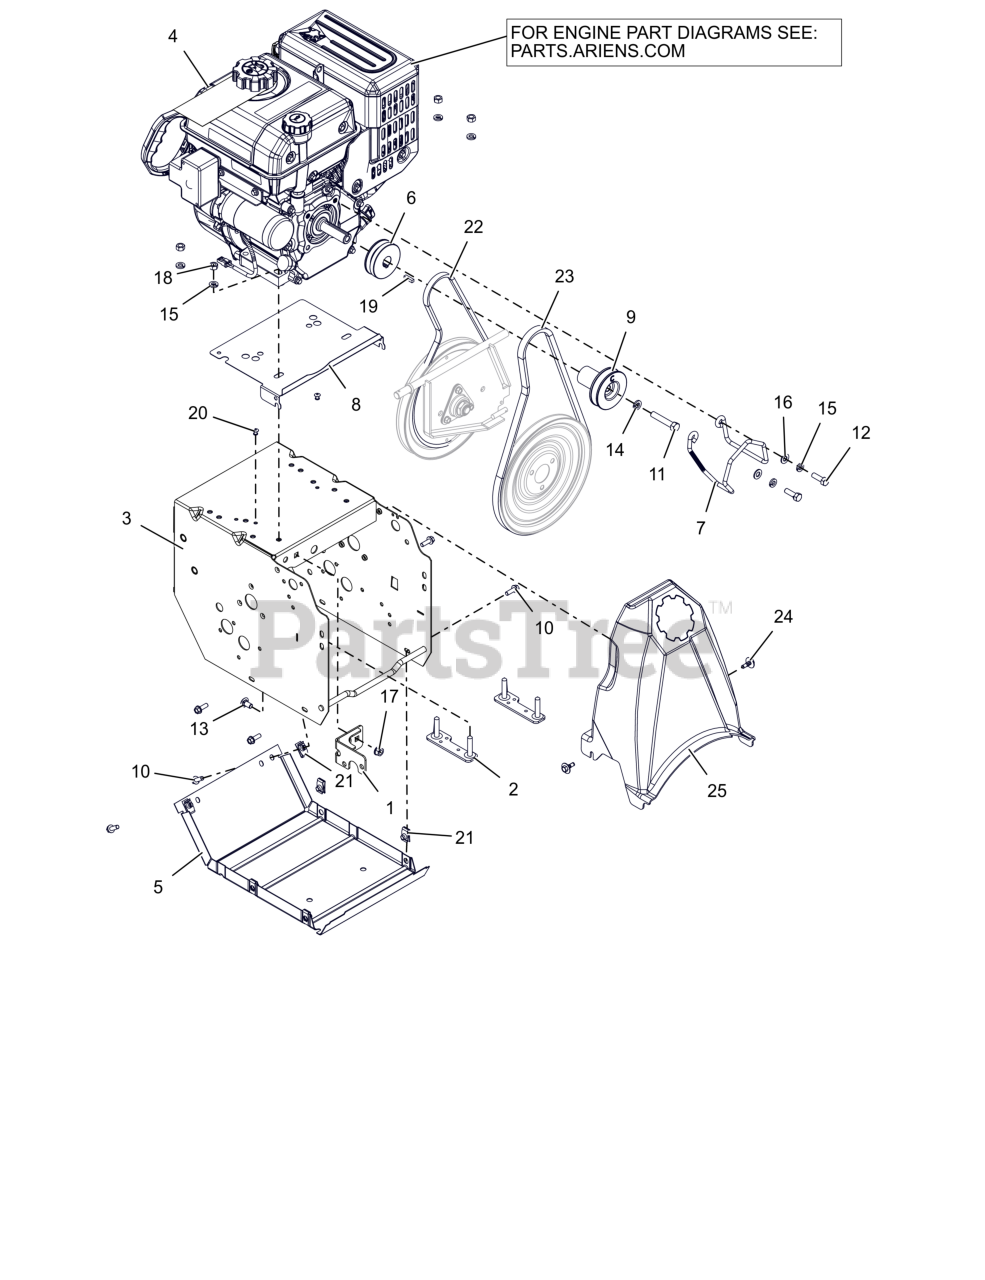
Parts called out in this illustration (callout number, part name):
1	WELDMENT, FRAME BRACKET
2	STRAP, ENGINE BOLT-WELDMENT
3	FRAME, MAIN-WELDMENT
4	ENGINE, ARIENS AX224 240V/60W
5	COVER, BOTTOM
6	SHEAVE, TRACTION-COMPACT TRACK
7	FINGER, BELT
8	BAFFLE- COMPACT
9	SHEAVE, ATTACHMENT SINGLE GRV
10	BLT, HWH .25-20X.75 G5 ZCC
11	BLT, HEX .38-24X2.00 G5 ZCC
12	BLT, HEX 0.3125-24X1 G5 ZCC
13	BLT, RHSSN .31-18X.625 G5 ZCC
14	WSHR,LK-REG .375X.094 ZCC
15	WSHR, LK-HVY .312X.097 ZCC
16	WSHR,FLT .344X.688X.065 ZCC
17	NUT-LK-TOP-FLG .312-18 GF ZCC
18	NUT, HEX .312-18 ZCC
19	KEY-SQ .188X.75X.188
20	RVT, POP .1875 ZCC
21	NUT-RTNR .25-20X.56
22	V-BELT, 3L-WRAPPED
23	V-BELT, HA-RAW EDGE
24	SCR-TAP .25-20X.5 CAPTIVE
25	COVER- CLASSIC BELT
